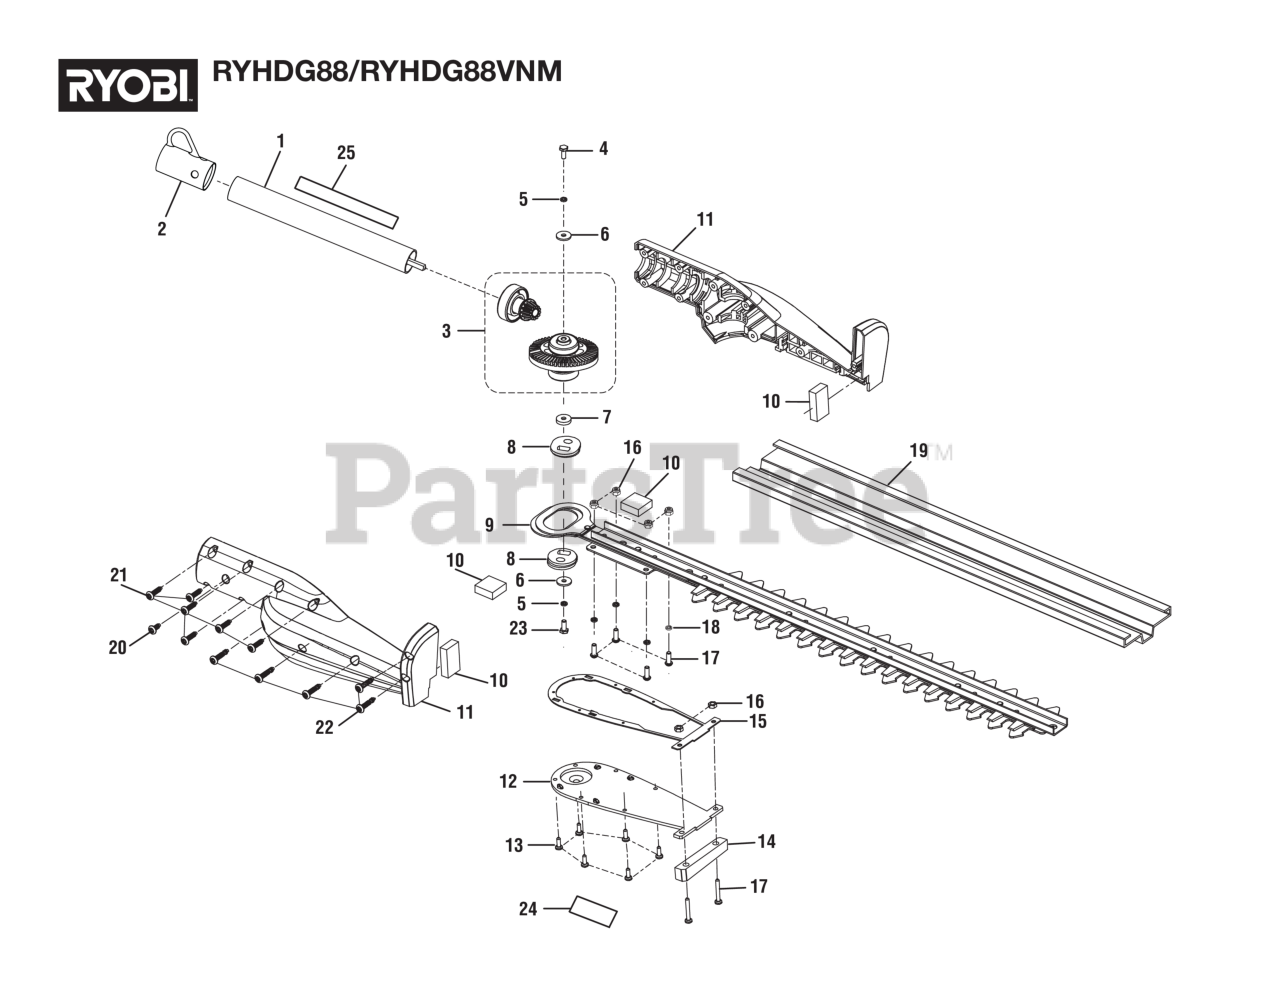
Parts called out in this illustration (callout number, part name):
1	Lower Drive Shaft Assembly
2	Hanger Cap
3	Output Gear and Pinion Assembly
4	Screw (M5 x 10 mm, Hex Hd.)
5	Lock Washer (ID5.1 x OD9 x 1.3t)
6	Washer (M5)
7	Cam Spacer
9	Blade Assembly
10	Felt
11	Housing Assembly
12	Bottom Housing Plate
13	Screw (M4 x 16 mm)
15	Seal
16	Lock Nut (M4)
17	Screw (M4 x 16 mm)
18	Spring Washer (M4)
20	Screw (M4 x 9 mm)
21	Screw (M5 x 14.5 mm)
22	Screw (M5 x 26.5 mm)
23	Screw (M5 x 12 mm, Hex Hd.)
24	Hot Surface Label
25	Warning Label
